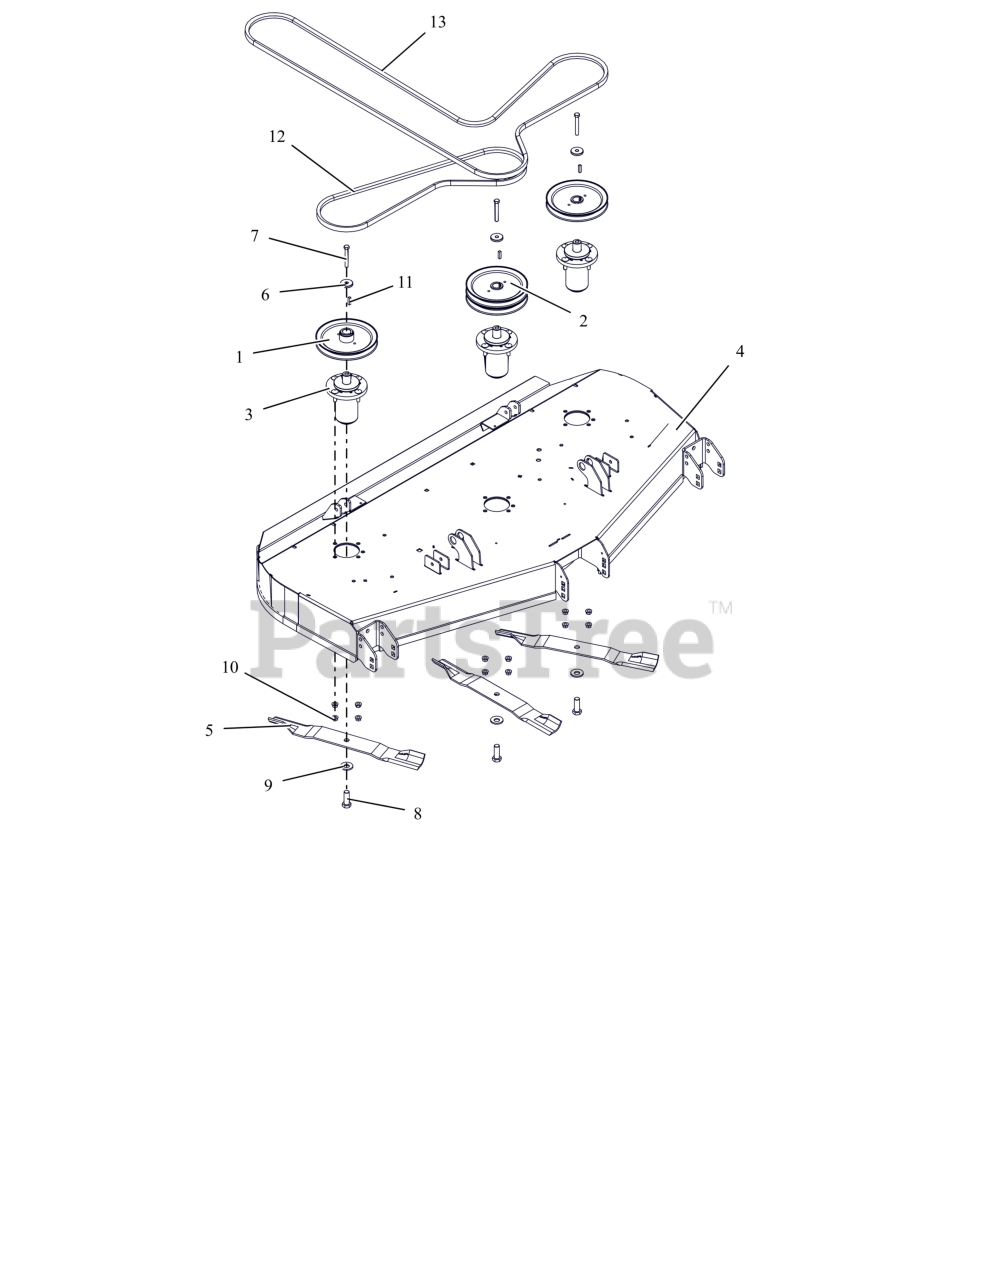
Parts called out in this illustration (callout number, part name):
1	PULLEY- V-7.50 OD X 1" ID
2	PULLEY- DOUBLE-1"X7.50"&7.50"
3	ASM, MAINT FREE ALUM SPINDLE
4	WLDMT, DECK 60 RD (ORANGE)
5	BLADE, 20.5"
6	RETAINER, SHEAVE
7	BLT, HEX .38-16X2.75 G8 ZCC
8	BLT, HEX .62-18X1.75 G8 ZCC
9	WSHR-BLVL .669X1.535X.138
10	NUT-LK-CTR-FLG .375-16 GF ZCC
11	KEY, SQ .25X.25X1.00 RC 40-50
12	V-BELT, B-COGGED
13	V-BELT, HB SECTION
